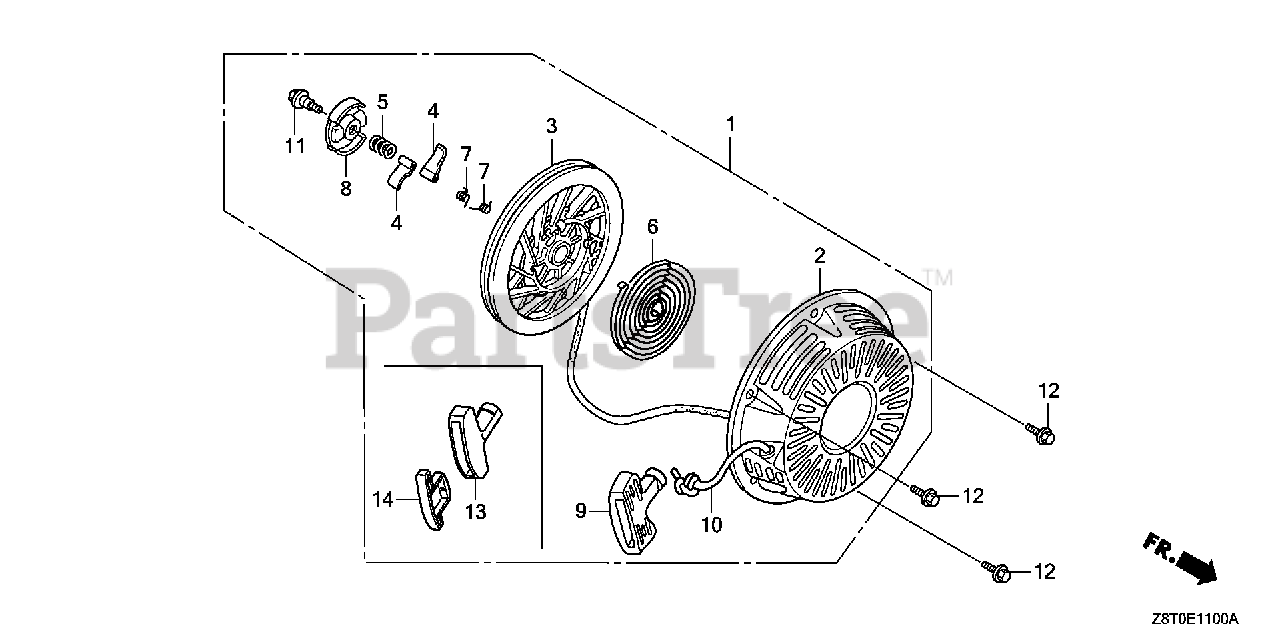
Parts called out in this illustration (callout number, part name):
1	STARTER ASSY., RECOIL *NH1* (BLACK)
2	CASE, RECOIL STARTER *NH1* (BLACK)
3	PULLEY, RECOIL STARTER
4	RATCHET, STARTER
5	SPRING, FRICTION
6	SPRING, STARTER RETURN
7	SPRING, RATCHET
8	RETAINER, SPRING
9	GRIP, STARTER
10	ROPE, RECOIL STARTER
11	SCREW, CENTER
12	BOLT, FLANGE (6X10)
